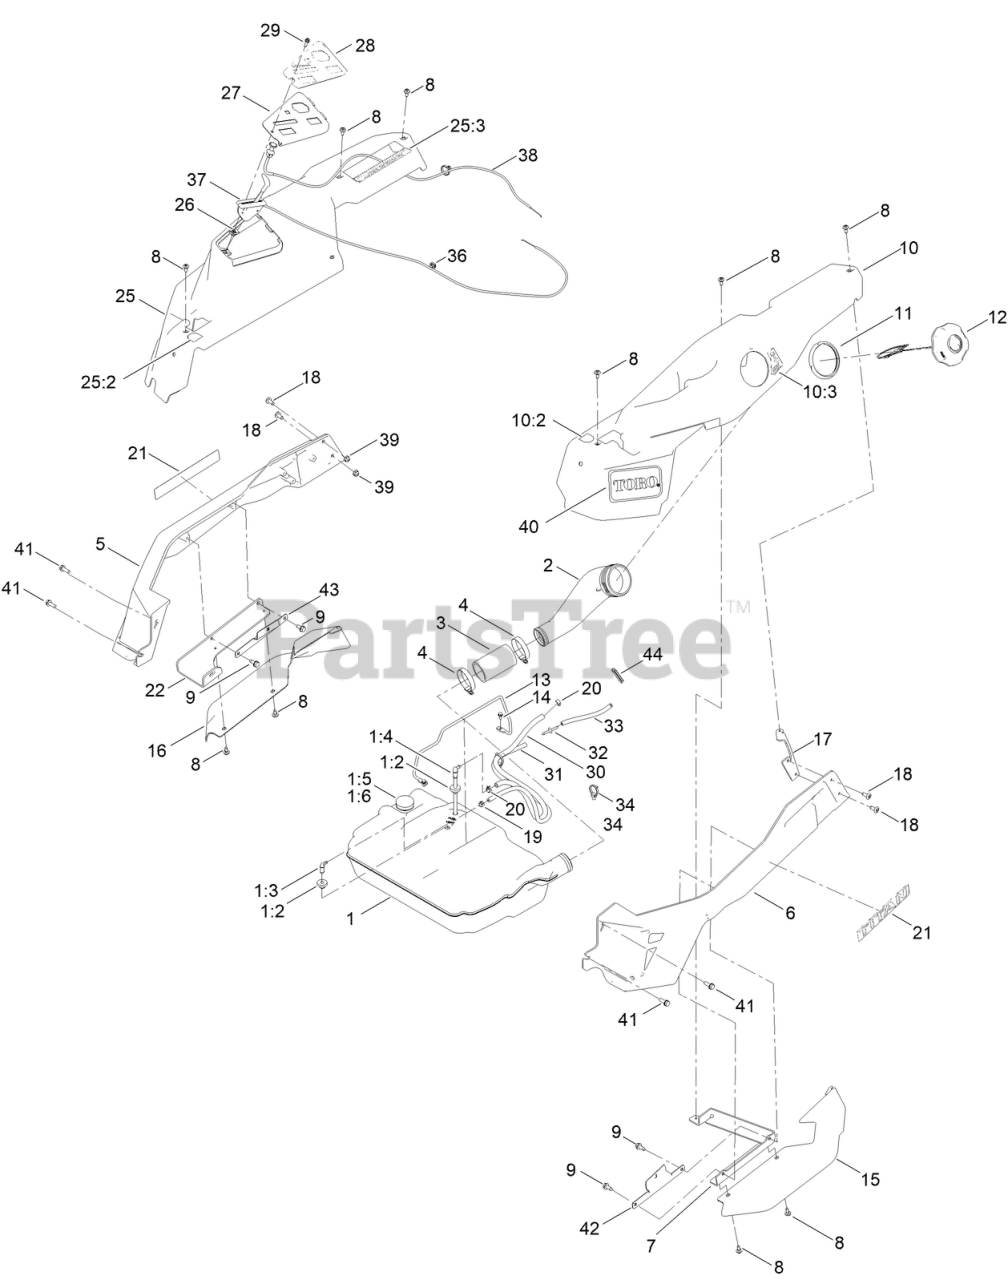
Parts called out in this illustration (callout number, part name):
1	TANK ASM - FUEL
1:2	BUSHING
1:3	FITTING-ELBOW 90
1:4	FITTING - PICKUP, FUEL
1:5	GROMMET-FUEL
1:6	REMOTE GAUGE ASM
2	NECK-FILLER, FUEL
3	HOSE-FILLER, FUEL
4	CLAMP-HOSE
5	CAST-TUBE, RH [RED]
6	CAST-TUBE, LH [RED]
7	MOUNT-POD BRACKET LH
8	SCREW-SHOULDER
9	SCREW-HWHTF
10	POD ASM - LH W/DECALS
10:2	DECAL-CONTROL LEVER, LH
10:3	DECAL-FUEL FILL
11	RING-RETAINING
12	CAP-FUEL, RATCHETING
13	ROD-HOLD DOWN
14	SCREW-HWH
15	FENDER-TIME CUTTER, LH
16	FENDER-TIME CUTTER, RH
17	BRACKET-REAR POD, LH
19	CLAMP-HOSE
20	CLAMP-HOSE
21	DECAL-TITAN
22	BRACKET-MR SPRING
25	POD ASM - RH , MR W/DECALS
25:2	DECAL-CONTROL LEVER, RH
25:3	DECAL - MYRIDE
27	PANEL-CONTROL
28	DECAL - CONTROL PANEL
29	SCREW-HWHTF
30	HOSE-FUEL
31	HOSE-FUEL
32	ADAPTER ORIFICE
33	HOSE-VENT
34	CLIP-TIE
36	CLIP-HARNESS
37	CABLE-THROTTLE
38	CABLE-CHOKE
39	NUT-HF
40	DECAL - TORO LOGO
41	SCREW-TAPTITE
42	BRACKET-ALIGNMENT, POD LH
43	BRACKET- ALIGNMENT, POD RH MR
44	TRIM-EDGE GUARD
